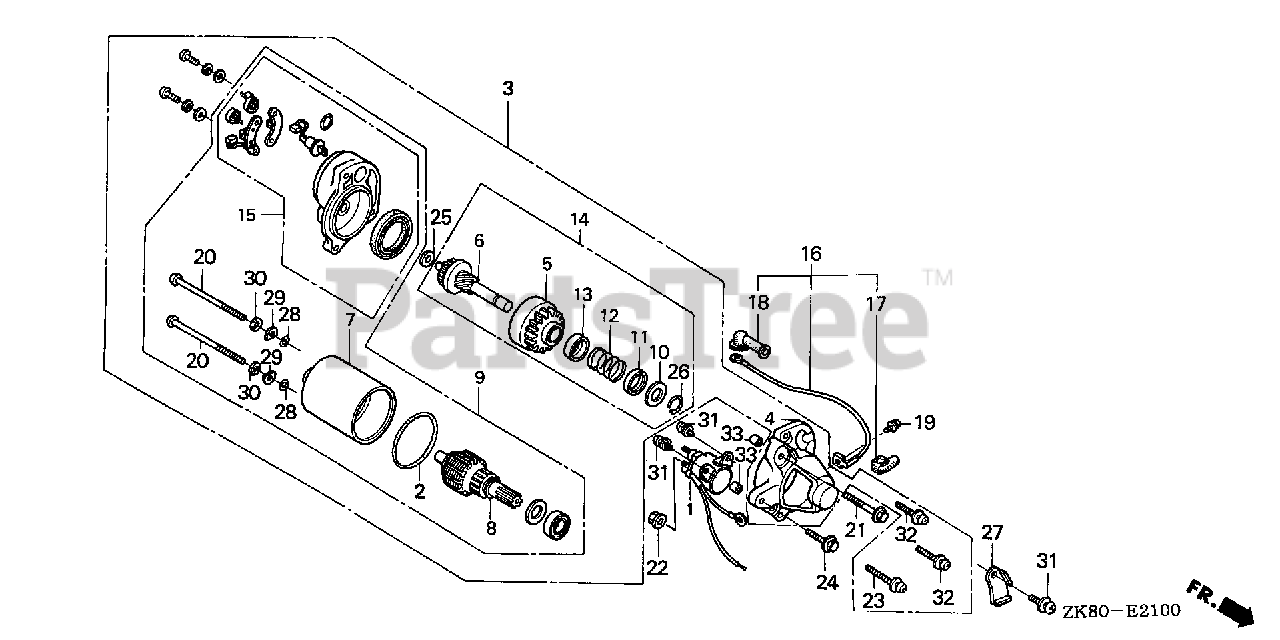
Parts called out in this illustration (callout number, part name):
1	SWITCH, STARTING MAGNET
1	SWITCH ASSY., STARTER MAGNETIC
2	O-RING
3	STARTER MOTOR UNIT (SM-11203) (162MM)
3	STARTER MOTOR UNIT (SM-11205) (181MM)
4	COVER, GEAR
5	PINION ASSY.
6	SHAFT UNIT, GEAR
7	YOKE ASSY.
8	ROTOR ASSY.
9	MOTOR ONLY
10	PIECE A, STOPPER
11	PIECE B, STOPPER
12	SPRING, RETURN
13	COVER, SPRING
14	GEAR ASSY.
15	BRACKET, FR.
16	WIRE, MAGNETIC SWITCH
17	COVER, MAGNETIC SWITCH
18	COVER, STARTER MOTOR TERMINAL
19	SCREW-WASHER (5X8)
20	BOLT, SETTING
21	BOLT, FLANGE (6X32) (CT200)
22	NUT-WASHER (6MM)
23	SCREW-WASHER (5X30)
24	BOLT, FLANGE (6X25) (CT200)
25	WASHER, PINION
26	CIRCLIP (10.2MM)
27	HOLDER, HARNESS
28	O-RING
29	WASHER, SPECIAL
30	WASHER, SPRING
31	SCREW-WASHER (5X14)
32	SCREW-WASHER (5X20)
33	PIN, DOWEL (8X10)
